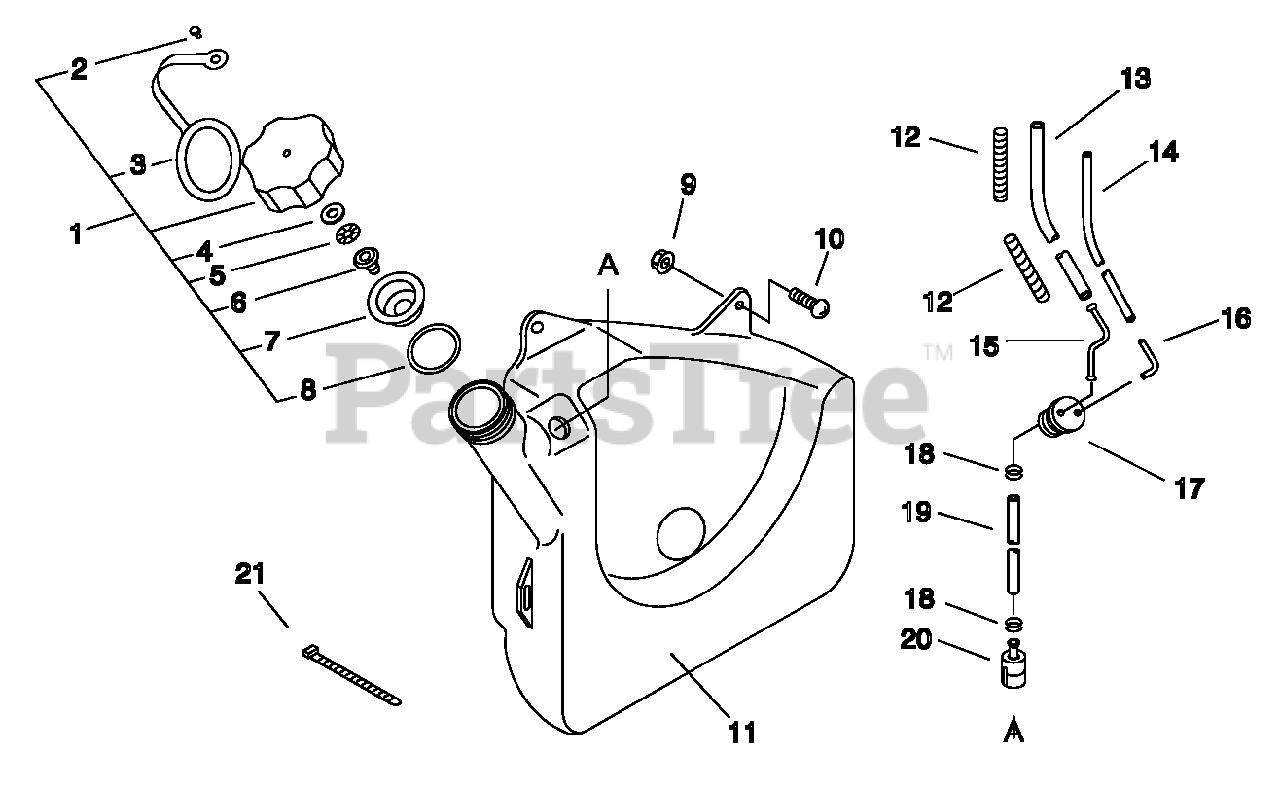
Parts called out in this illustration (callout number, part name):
1	CAP ASSY, FUEL
3	CONNECTOR, CAP
4	WASHER 3 MM
6	VENT ASSY
7	HOLDER, VENT
8	GASKET, FUEL CAP
9	NUT, FLANGE M5
10	SCREW 5×20
11	TANK, FUEL
12	TUBE, SPIRAL
14	PIPE, FUEL 2×4×470 CLEAR
15	CONNECTOR, PIPE
16	CONNECTOR, PIPE
17	GROMMET
18	CLIP 6.5 MM
19	PIPE, FUEL 3×6×280 MM
20	FILTER, FUEL
21	STRAP, TIE
